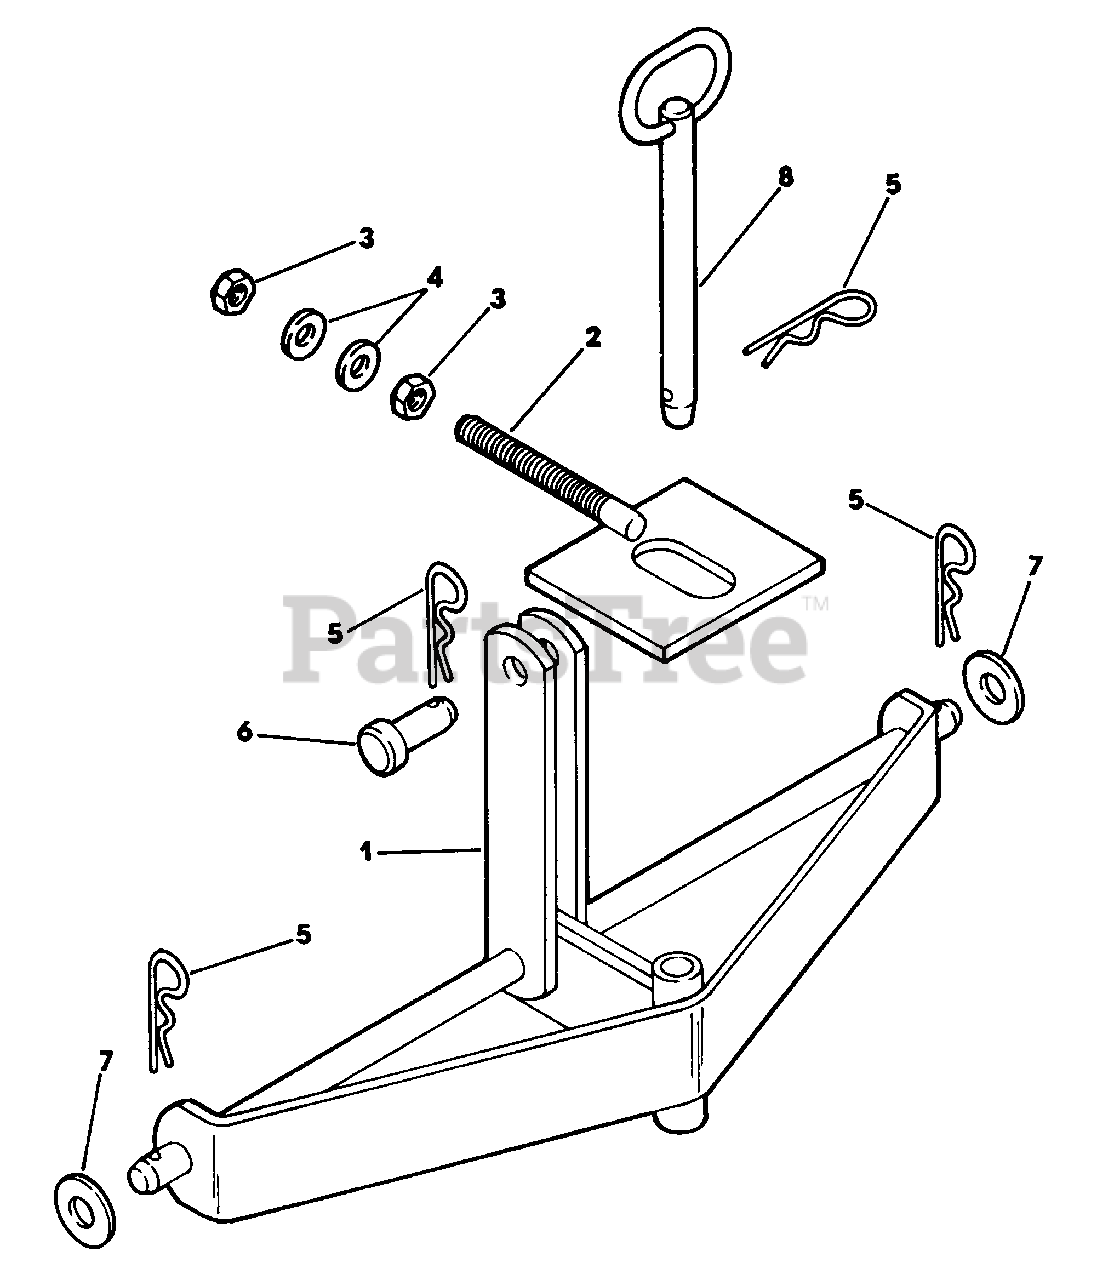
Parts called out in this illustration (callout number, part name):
1	Adaptor Assembly-"O" Hitch
2	Adjustment Plate
3	Nut, Hex
4	Washer, Flat
5	Spring Clip
6	Pin, Clevis
7	Washer, Flat
8	Hitch Pin Assembly
